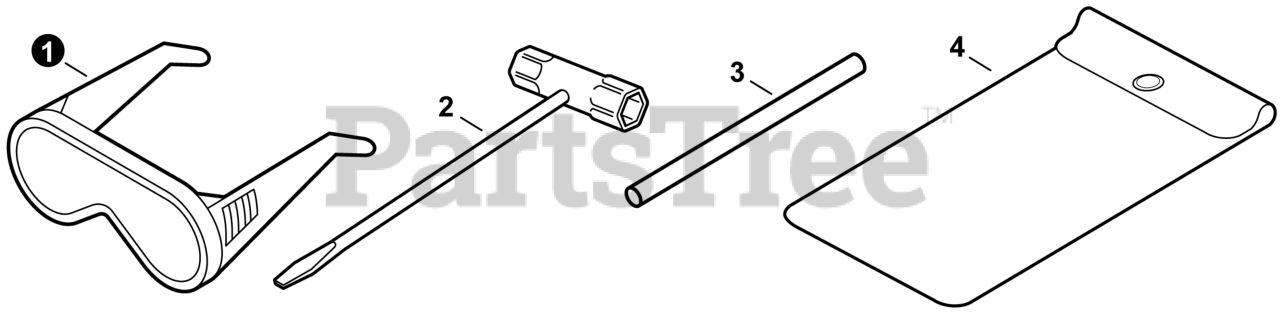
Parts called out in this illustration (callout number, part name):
1	GLASSES, SAFETY
2	T-WRENCH 17x19 L200
3	TOOL, LOCKING 5x120 MM
4	BAG, TOOL
